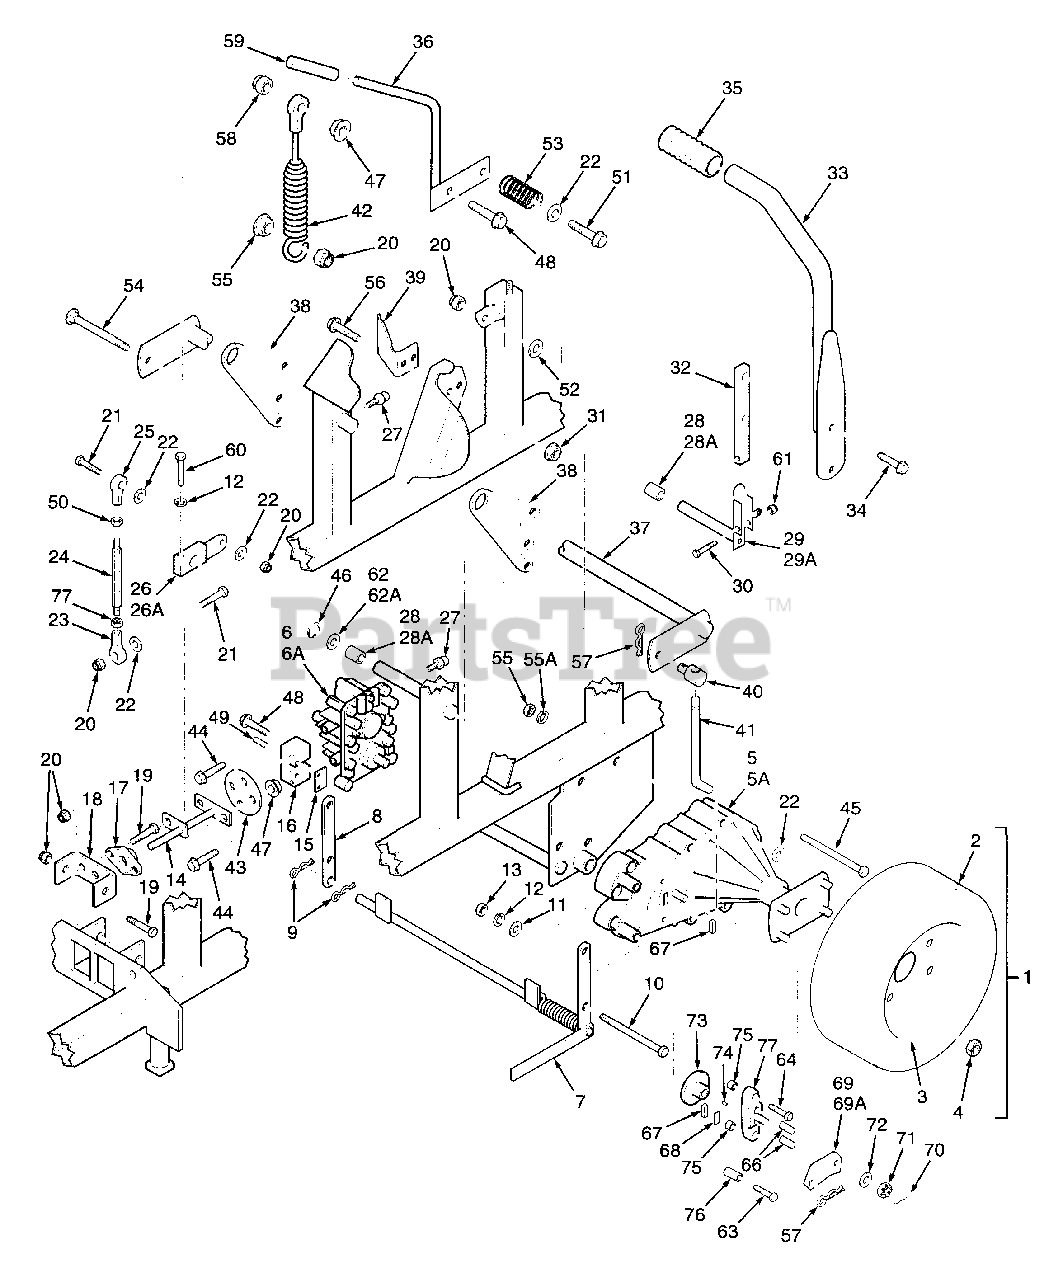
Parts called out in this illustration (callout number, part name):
1	Drive Wheel Assembly
1	Drive Wheel Assembly (SSZ-LT-48)
2	Tire Only
3	Rim Only
4	Lug Nut, 1/2-20
5	Axle, LH
5A	Axle, RH
6	Pump, LH
6A	Pump, RH
7	Dump Valve, Lever Weldment
8	Bracket, Mounting
9	Hair Pin
10	Bolt, Hex Head 5/16-18 x 5"
14	Pump Weldment Shaft
15	Clamp Plate
16	Block, Pump Control
17	Bushing, Self Align
18	Bracket, Bearing
22	Flatwasher, 3/8" Special
23	Ball Joint, LH Thread
24	Link, Turnbuckle
25	Bail Joint, RH Thread
26	Lever, Pump Transfer LH
26A	Lever, Pump Transfer RH
27	Grease Fitting
28	Bushing, LH
28A	Bushing, RH
29	Control Lever, LH
29A	Control Lever, RH
31	Nut, Serrated Flange Hex 5/16-18
32	Bar Control Lever
33	Control Handle
34	Bolt, Serrated Flange Hex Head 3/8-16 x 1"
35	Grip, Control Handle
36	Lever Weldment, Parking Brake
37	Cam Weldment, Parking Brake
38	Plate, Parking Brake
39	Latch, Brake
40	Swivel Joint
41	Rod, Brake
42	Cable Assembly, Parking Brake
43	Plate, Coupler
44	Bolt, Serrated Flange Hex Hd 1/4-20 x 3/4"
45	Bolt, Hex Head 3/8-16 x 4", grade 8
46	Ring, Retaining 3/4" External "E"
47	Nut, Serrated Flange Hex 1/4-20
49	Roll Pin, 3/16 x 3/4"
52	Flatwasher, 3/8 (.375 x 1-1/2" x 16 ga.)
53	Spring, Brake Lever
55	Nut, Elastic Stop 3/8-16
55A	Lockwasher, 3/8" spring, grade 8
56	Bolt, Serrated Flange Hex Head 5/16-18 x 3/4"
57	Hair Pin, 1/16"
59	Grip, Parking Brake
61	Nut, Elastic Stop 5/16-18
62	Flatwasher, 3/4"
62A	Flatwasher, 3/4" Special
63	Bolt, 1/4-20 x 2-1/2 GR. 5 w/patch
64	Bolt, 1/4-20 x 1-1/2 GR. 5 w/patch
66	Pins, Actuating
67	Brake Puck
68	Backing Plate
69	Actuating Lever, RH
69A	Actuating Lever, LH
70	Pin, Cotter
71	Nut, Castle
72	Washer, 7/16 x 7/8 OD x .06 HT
73	Disc, Brake
74	Key, Hi Pro 3/16 x 5/8
75	Brake Spacer
76	Spacer, Torsion Spring
77	Brake Yoke Assembly
